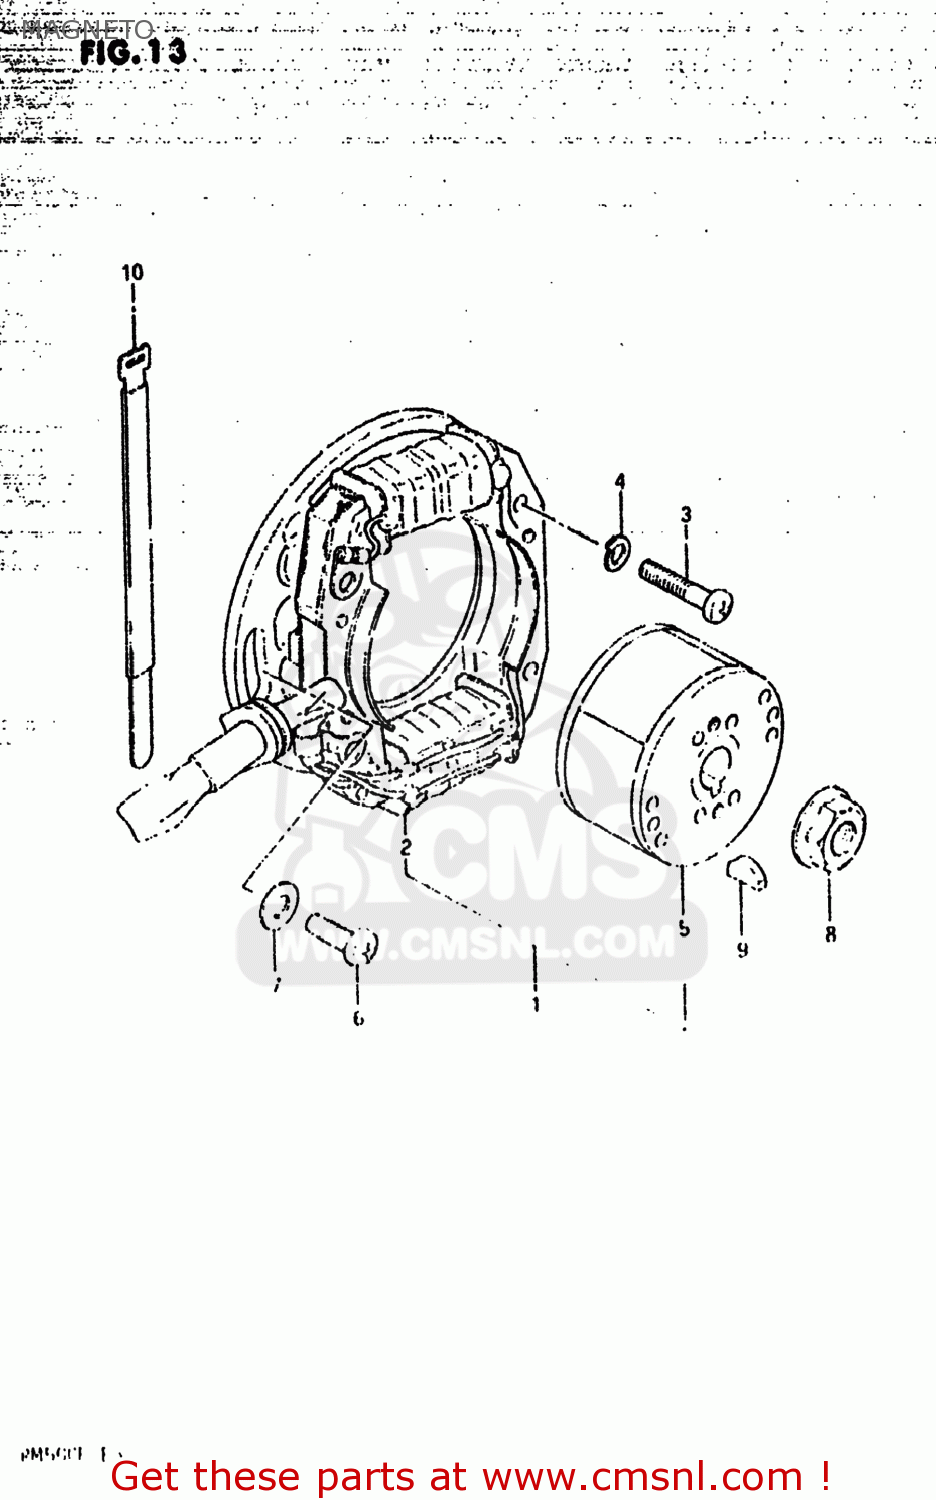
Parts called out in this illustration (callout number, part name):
1	MAGNETO ASSEMBLY
2	STATOR ASSEMBLY
3	SCREW 5X20
4	LOCK WASHER
5	ROTOR ASSEMBLY
6	SCREW
7	WASHER
8	NUT
9	KEY 4MM
10	CLAMP(L:250)
